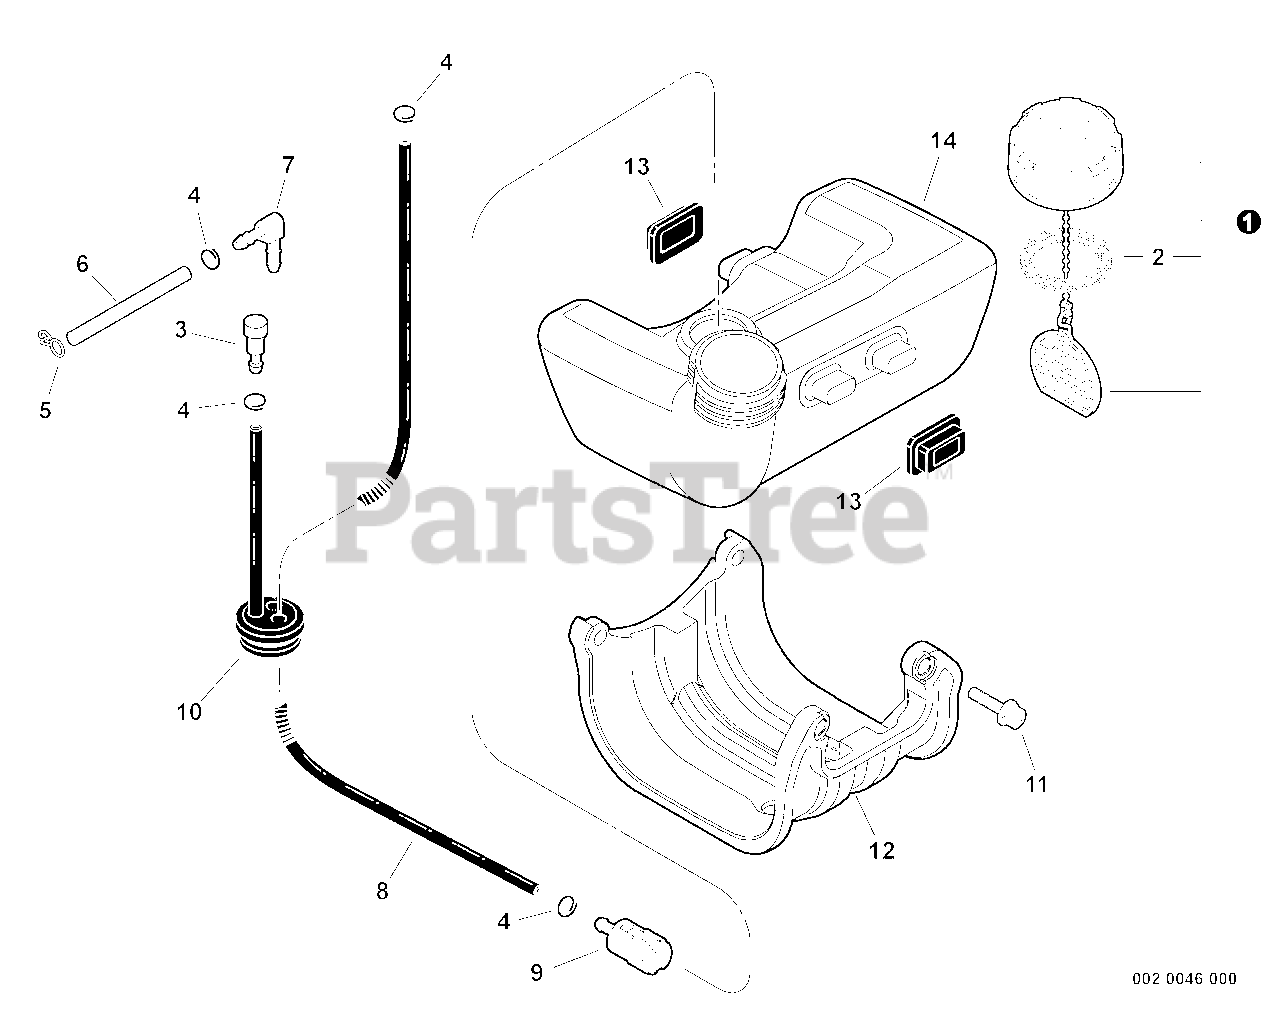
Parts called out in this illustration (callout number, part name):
1	CAP ASSY - RED
2	GASKET, CAP
3	VENT, FUEL TANK
4	CLIP - 6
5	CLIP - BUTTERFLY
6	PIPE - CLEAR
7	CONNECTOR, PIPE
8	PIPE - BLACK
9	FILTER, FUEL
10	PIPE ASSY
11	SCREW - 5X20
12	GUARD, FUEL TANK
13	CUSHION, FUEL TANK
14	TANK, FUEL
